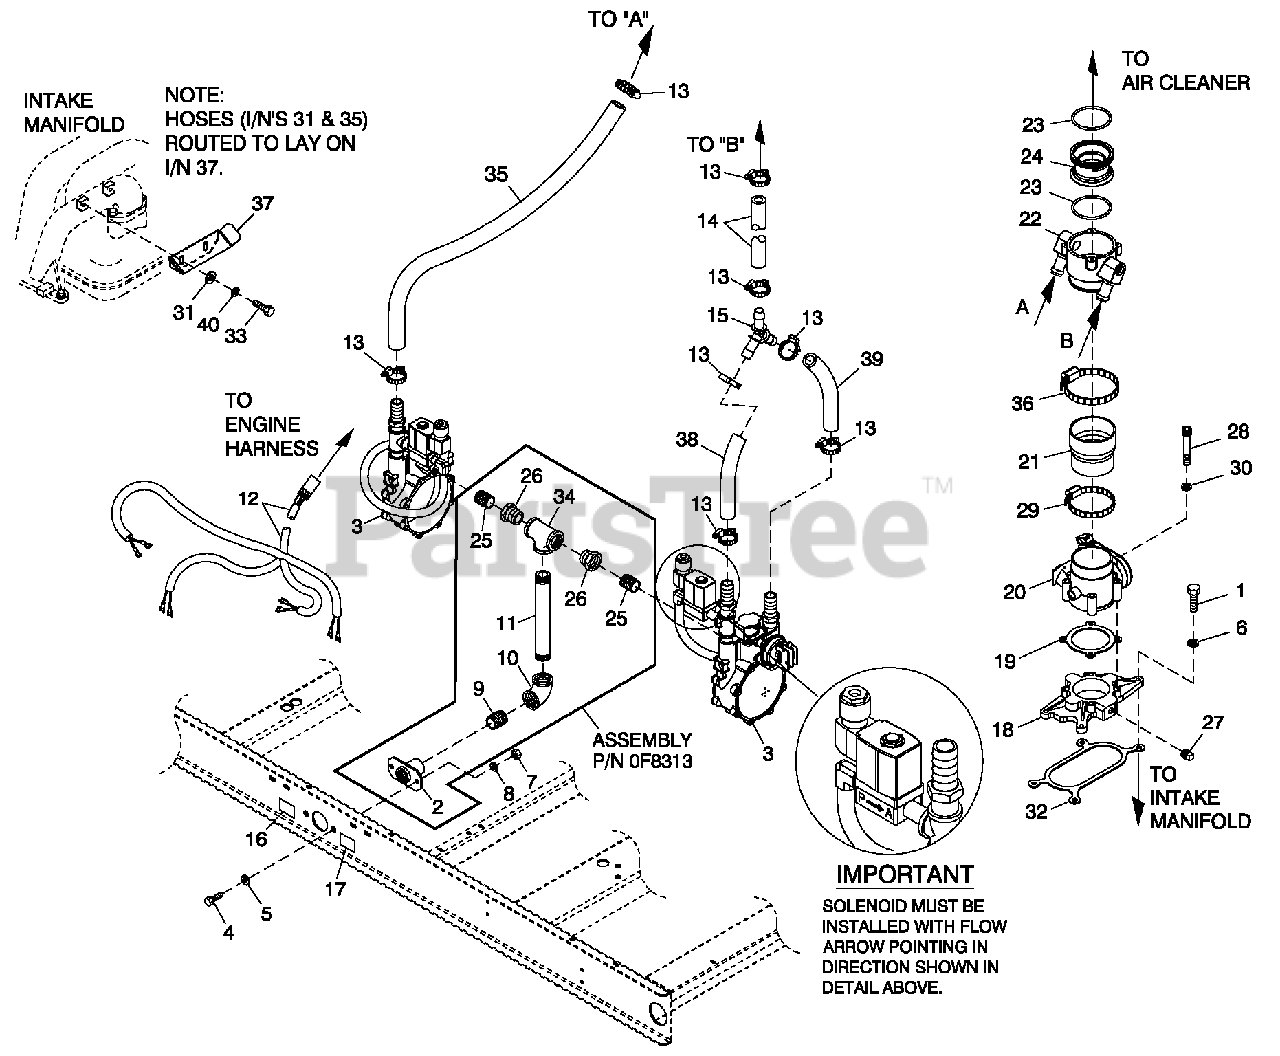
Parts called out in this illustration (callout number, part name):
1	SCREW HHC 5/16-18 X 1-1/4 G5
2	SUPPORT NAT GAS SOLENOID
3	REG ASSY 5.4L 80KW NG CPL
4	SCREW HHC #12-1.75 X 20 G8.8
5	WASHER FLAT 1/2 ZINC
6	WASHER LOCK M8-5/16
7	NUT HEX M12-1.75 G8 YEL CHR
8	WASHER LOCK 1/2
9	NIPPLE CLOSE 1.25 NPT X 1.625
10	ELBOW 90D 1-1/4 NPT
11	NIPPLE PIPE 1-1/4 NPT X 3 (100 KW)
12	HARNESS, FUEL JUMPER DUAL REG
13	CLAMP HOSE #8 .53-1.00
14	HOSE 3/4 ID SAE-30R2 (42" LG)
15	Y CONNECTOR 500 SERIES BARBS
16	DECAL INLET PRESSURE
17	DECAL FUEL INLET NG
18	ASSY,ADAPTER,THROTTLE BODY
19	GASKET GOVERNOR ACTUATOR
20	ACTUATOR BOSCH 60 GOVERNOR
21	REDUCER 3.0" TO 2.75" TURBO
22	MIXER 40/60MM ACTUATOR ASSY
23	O-RING 2-3/4X3/32X2-15/16
24	VENTURI, THROTTLE 42MM (100 KW)
25	NIPPLE CLOSE 3/4 X 1.375
26	BSHG RDCR HEX 1-1/4-3/4
27	PLUG STD PIPE 1/4 STEEL SQ HD
28	SCREW SHC M6-1.0 X 50 C8.8
29	CLAMP HOSE #44 2.31-3.25
30	WASHER LOCK M6-1/4
31	WASHER FLAT M6
32	GASKET ADAPTER THROT BODY
33	SCREW HHC M6-1.0X 20 G8.8
34	PIPE TEE 1-1/4 NPT
35	HOSE 3/4 ID SAE-30R2 (45" LG)
36	CLAMP HOSE #52 2.81-3.75
37	BRACKET, HOSE RISER
38	HOSE 3/4 ID SAE-30R2 (9.5" LG)
39	HOSE 3/4 ID SAE-30R2 (12" LG)
40	WASHER LOCK M6-1/4
